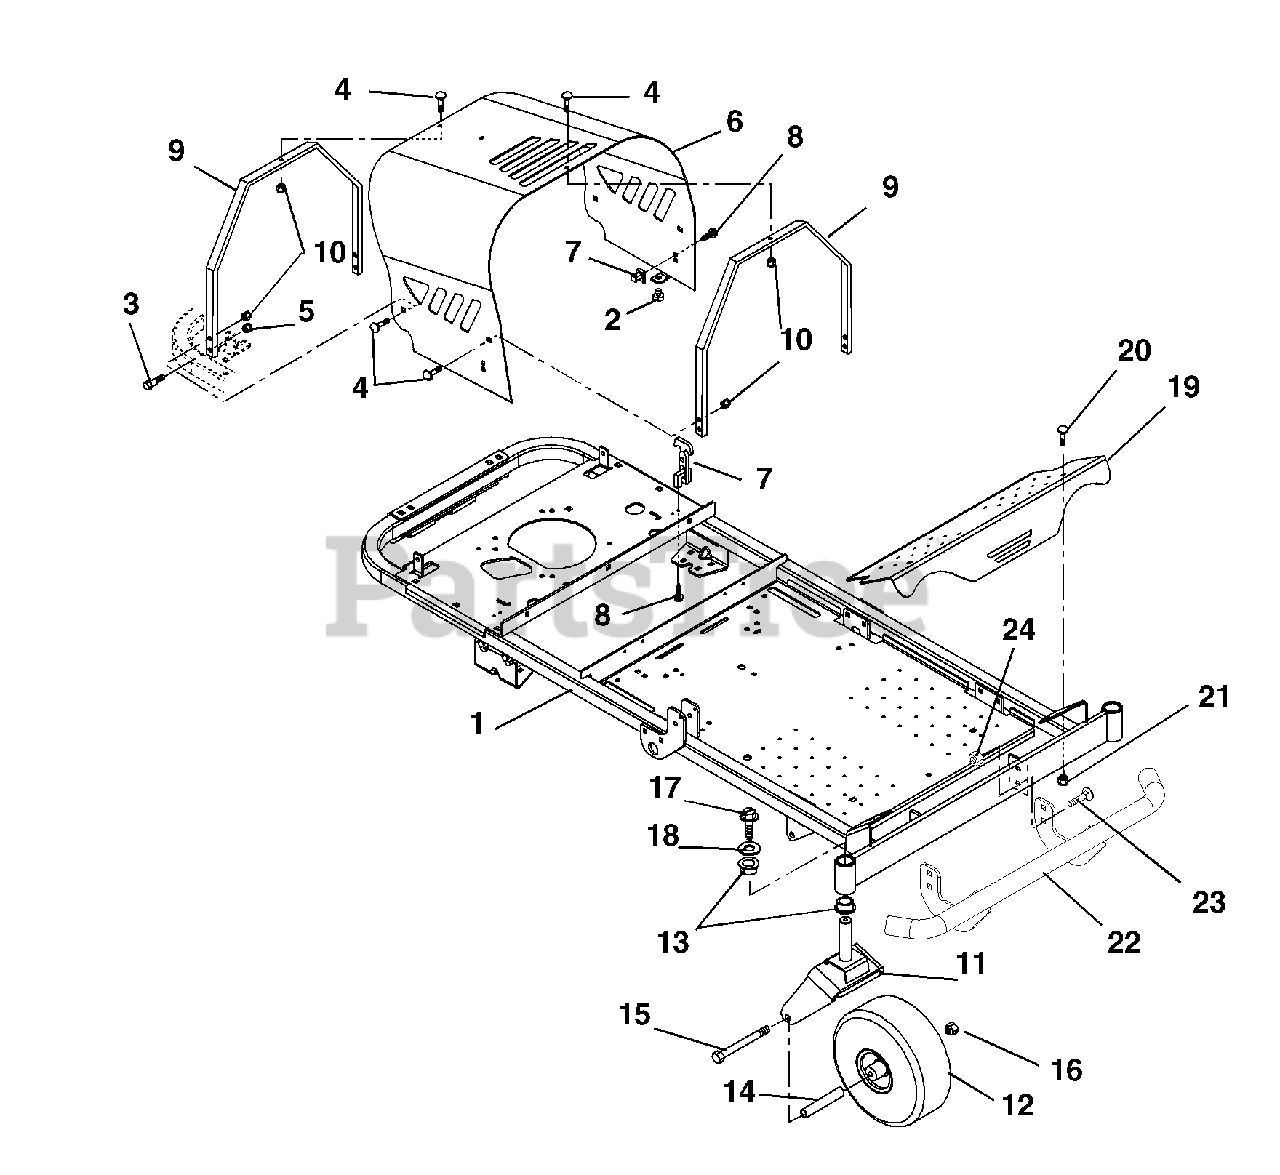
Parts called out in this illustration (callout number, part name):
1	WMT, FIXED AXLE FRAME
2	BUTTON BUMPER
3	BOLT-SHLDR .375-16X.150
4	@BLT-RHDSSQNK .31-18X.62 G5YZ
5	@NUT-LK-TOP-FLG .38-16 YWZC
6	HOOD, ZOOM
7	LATCH, RUBBER
8	@SCR-MCH 10-24X.50 HWH YWZC
9	BRACE, HOOD
10	@NUT-LK-TOP-FLG .31-18 YWZC
11	FORK - CASTER
12	ASSY-TIRE 4 X 11 - 4 PLY
13	BSHG-FLG 1.00X1.25X1.50X1.50EP
14	BUSH.,CASTER FORK
15	@BLT-HEX .50-13X6.50 GR5 YWZC
16	@NUT-LK-TOP-FLG .50-13 YWZC
17	SCR-TAP .38-16X1.25 HWH TR BZC
18	WSHR-FL-STL .380X1.50X.125YWZC
19	FOOT REST
20	@BLT-RDHDSQNK .38-16X1.00 G5YZ
21	@NUT-LK-NYL-FLG .38-16 YWZC
22	BUMPER-ZOOM
23	@BLT-RDHDSQNK .38-16X1.00 G5YZ
24	@NUT-LK-NYL-FLG .38-16 YWZC
